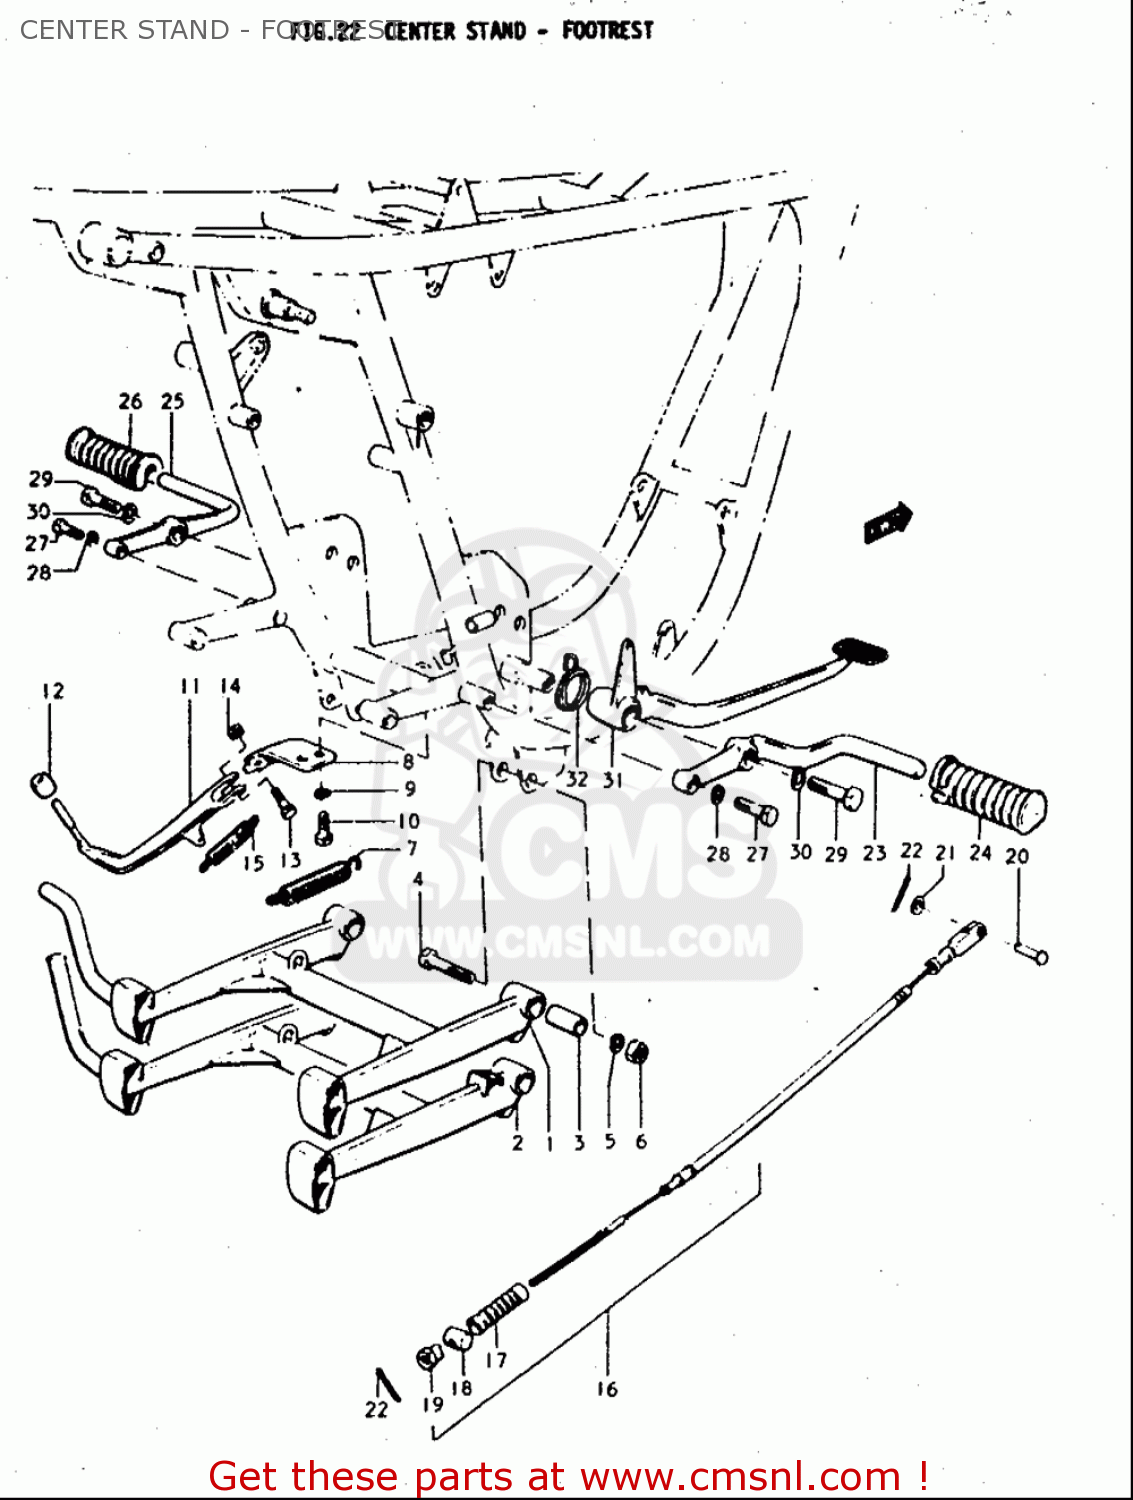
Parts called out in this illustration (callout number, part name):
3	SPACER(10.5X16X30)
4	BOLT(10X48)
5	WASHER,LOCK
6	NUT
7	SPRING
8	BRACKET,SIDE STAND
9	WASHER,LOCK
10	BOLT
11	STAND,PROP
12	CUSHION
13	BOLT(10X27)
14	NUT
15	SPRING
16	CABLE ASSY,RR BRAKE
17	SEAL,DUST
18	PIN(13X18)
19	NUT
21	WASHER
24	RUBBER,FR FOOTREST,R
26	RUBBER,FR FOOTREST
28	WASHER,LOCK
29	BOLT
30	WASHER,LOCK
32	SPRING
